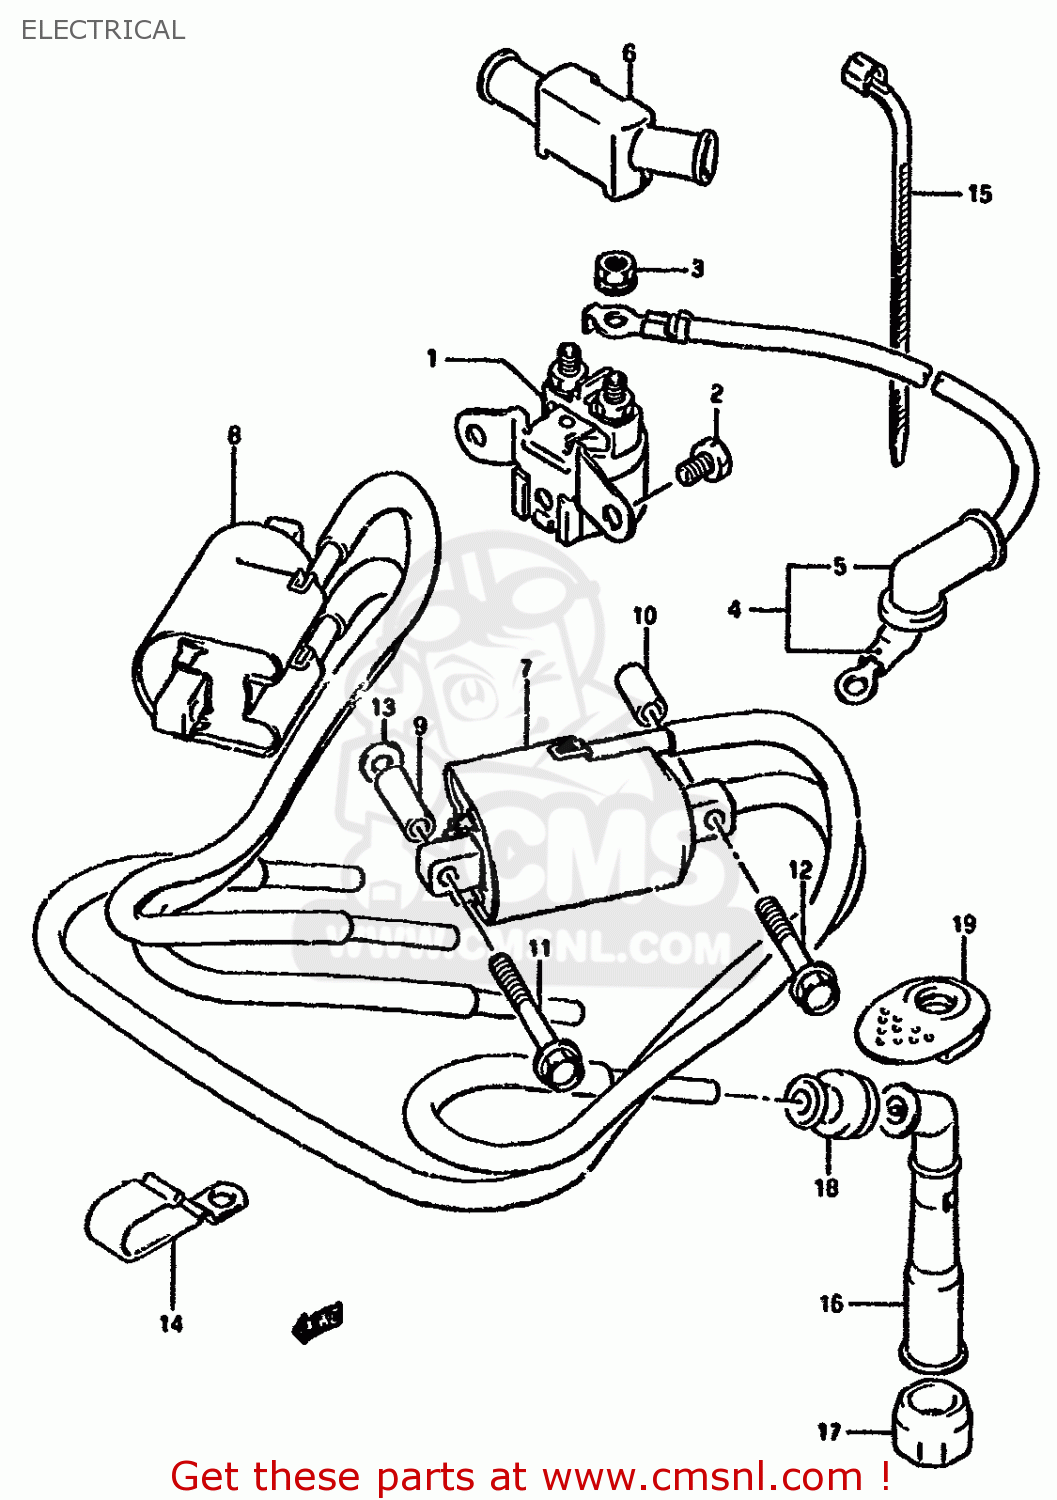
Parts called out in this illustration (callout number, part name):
1	RELAY ASSY,STARTING MOTOR
2	SCREW(6X8)
3	NUT
4	WIRE,STARTER MOTOR LEAD
5	CAP,STARTER MOTOR LEAD
6	CAP,STARTER RELAY
7	COIL ASSY,IGNITION
8	COIL ASSY,IGNITION
9	SPACER(6.4X10X28)
10	SPACER(6.4X10X18)
11	BOLT
12	BOLT
13	WASHER
14	CLAMP
15	CLAMP(L:125)
16	CAP,SPARK PLUG
17	SEAL,SPARK PLUG
18	SEAL,HIGH TENSION CORD
19	COVER,SPARK PLUG CAP
